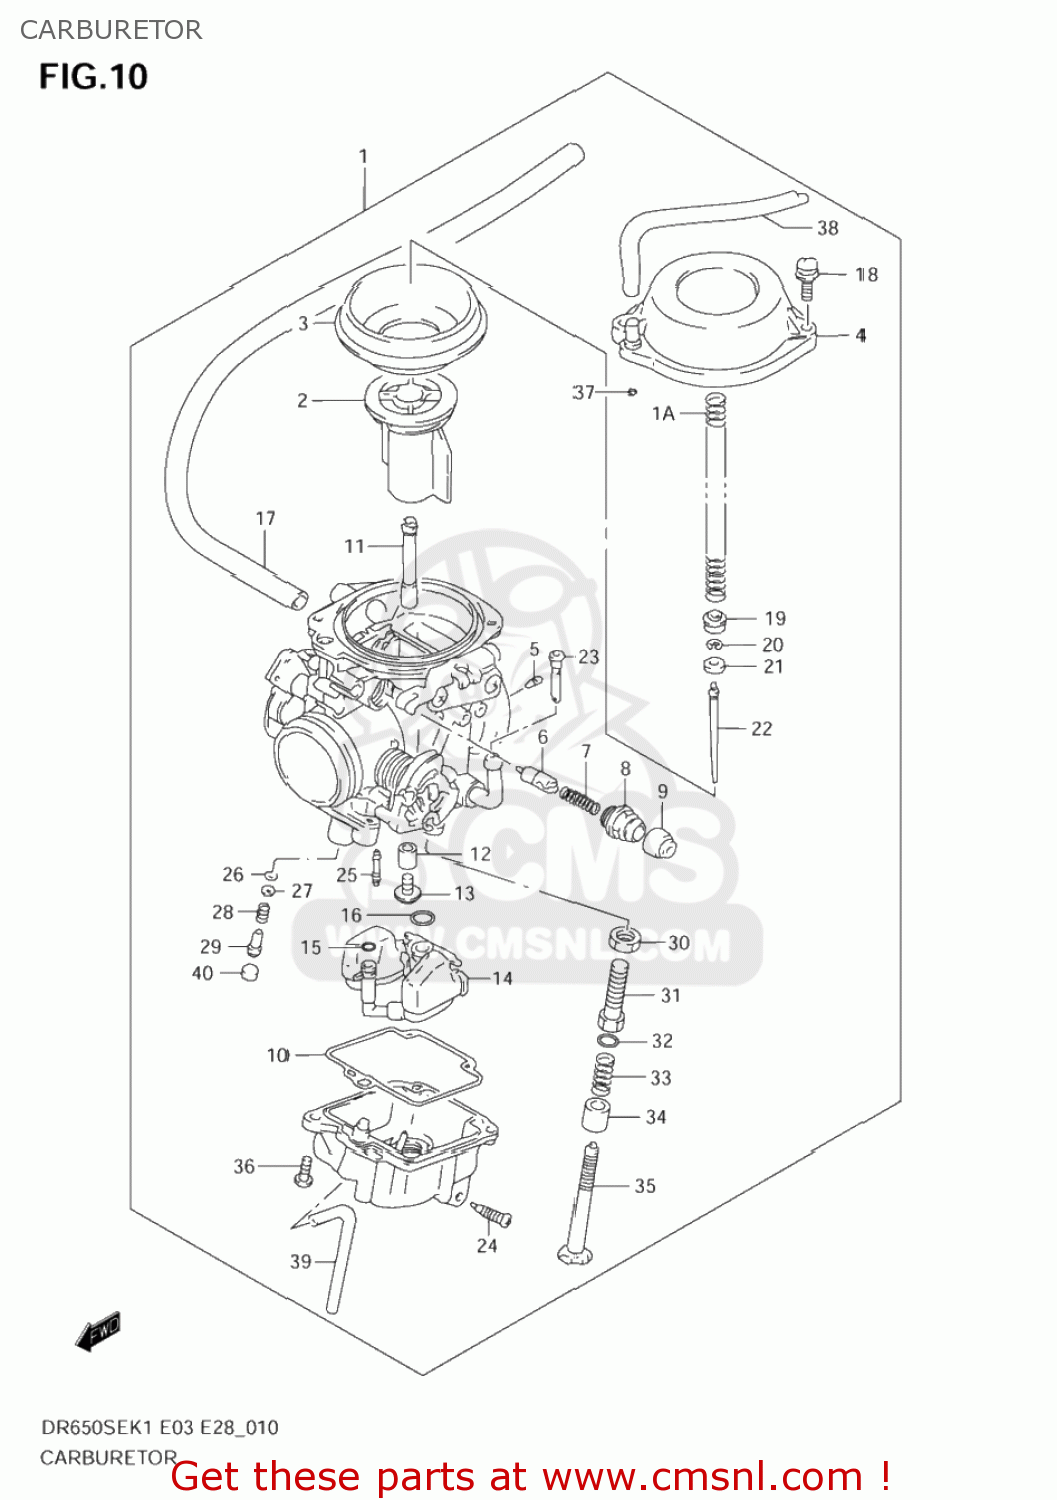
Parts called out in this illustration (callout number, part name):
1	CARBURETOR ASSY
1A	SPRING
2	VALVE,PISTON
3	DIAPHRAGM
4	COVER,DIAPHRAGM
5	JET,AIR(1.0)
6	PLUNGER
7	SPRING
8	HOLDER,GUIDE
9	CAP
10	GASKET,FLOAT CHAMBER (NAS)
11	JET,NEEDLE(Y-5M)
12	RING
13	JET,MAIN(140)
14	FLOAT/NEEDLE VALVE ASSY
15	O RING
16	O RING,NEEDLE VALVE SEAT
17	HOSE(6.5X10.5X275)
18	SCREW
19	RING
20	CLIP,NEEDLE
21	RING
22	NEEDLE,JET(6F23)
23	FILTER
24	SCREW,DRAIN
25	JET,PILOT(42.5)
26	O RING,PILOT AIR SCREW
27	WASHER
28	SPRING
29	SCREW,PILOT
30	NUT
31	ADJUSTER
32	WASHER,STARTER SHAFT
33	SPRING
34	RING
35	ADJUSTER
36	SCREW(5X14)
37	O RING
38	HOSE(4.5X8.5X600)
39	HOSE(3X5X450)
40	PLUG
